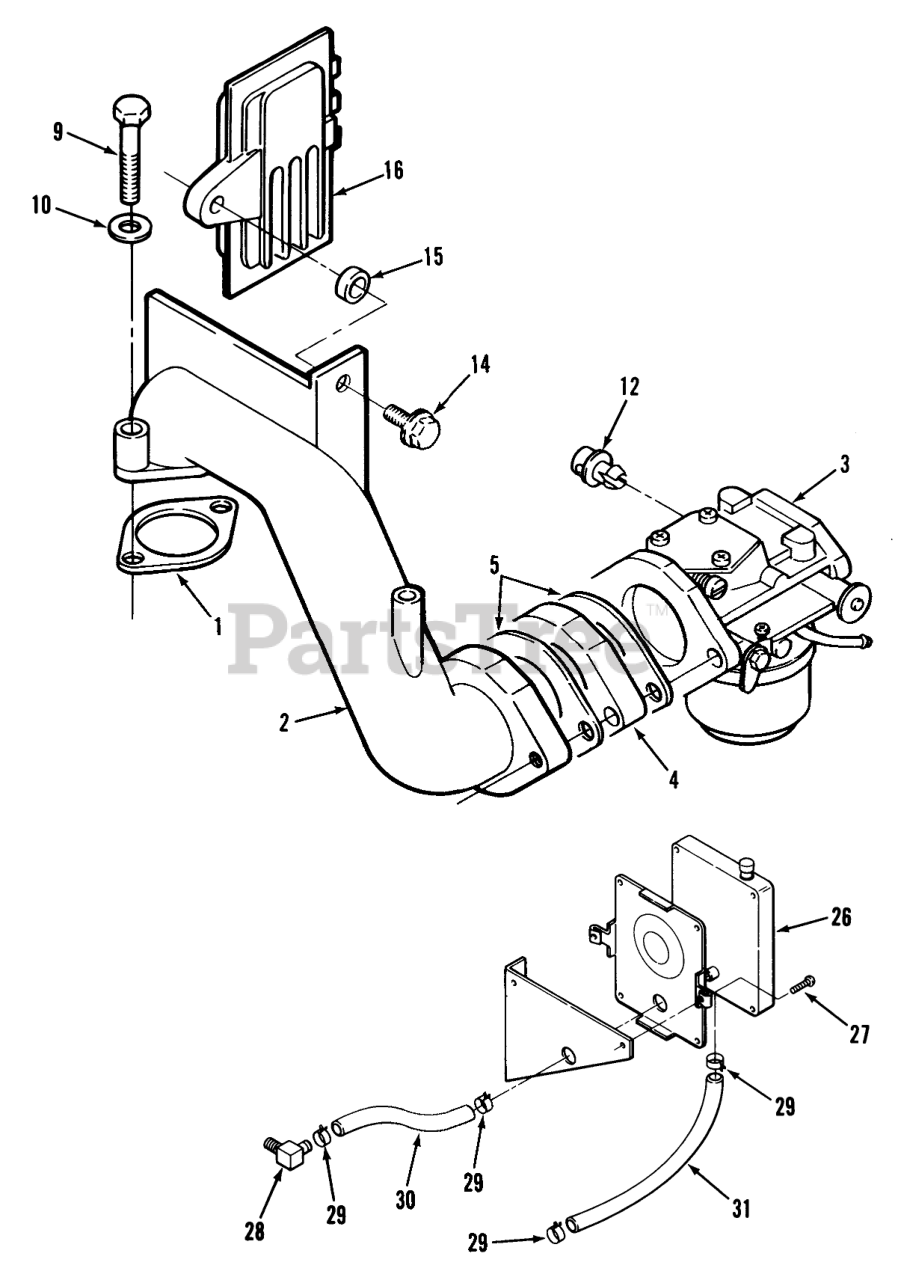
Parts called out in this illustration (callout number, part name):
1	Gasket
2	Elbow-Intake
3	CARBURETOR
4	INSULATOR
5	Gasket
9	HHCS-M8 X 50MM
10	Nut-M8
12	Clip
14	SCHWH 1/4-20X 7/8 SB
15	Bushing
16	Regulator
26	PUMP-FUEL
27	STFHWH M4 X 4MM
28	Elbow 90deg. 1/8"
29	Clamp
30	Hose
31	Hose 5 1/2" x 1/4 ID
